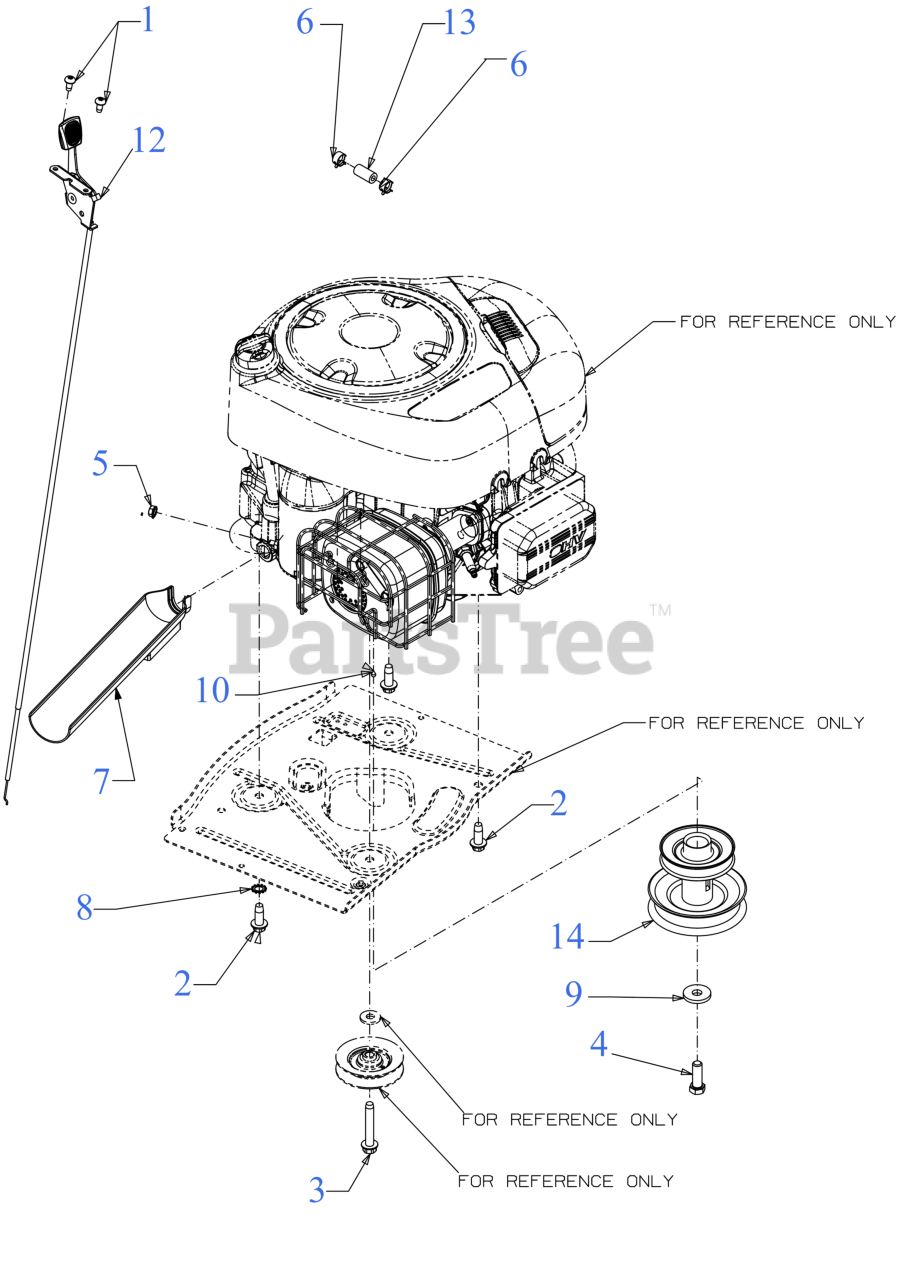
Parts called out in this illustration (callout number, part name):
1	SCREW 1/4-20 x .500
2	SCREW 3/8-16 x 1
3	SCREW 3/8-16 x 2.250
4	SCREW 7/16-20 x 1.250 GR5
5	SEMS NUT 1/4-20
6	HOSE CLAMP 1/20
8	LOCK WASHER 3/8
9	FLAT WASHER .445 x 1.248 x .170
12	THROTTLE CABLE 31" x 1.1
13	FUEL HOSE LOW PERMEATION 16"
14	ENGINE PULLEY
